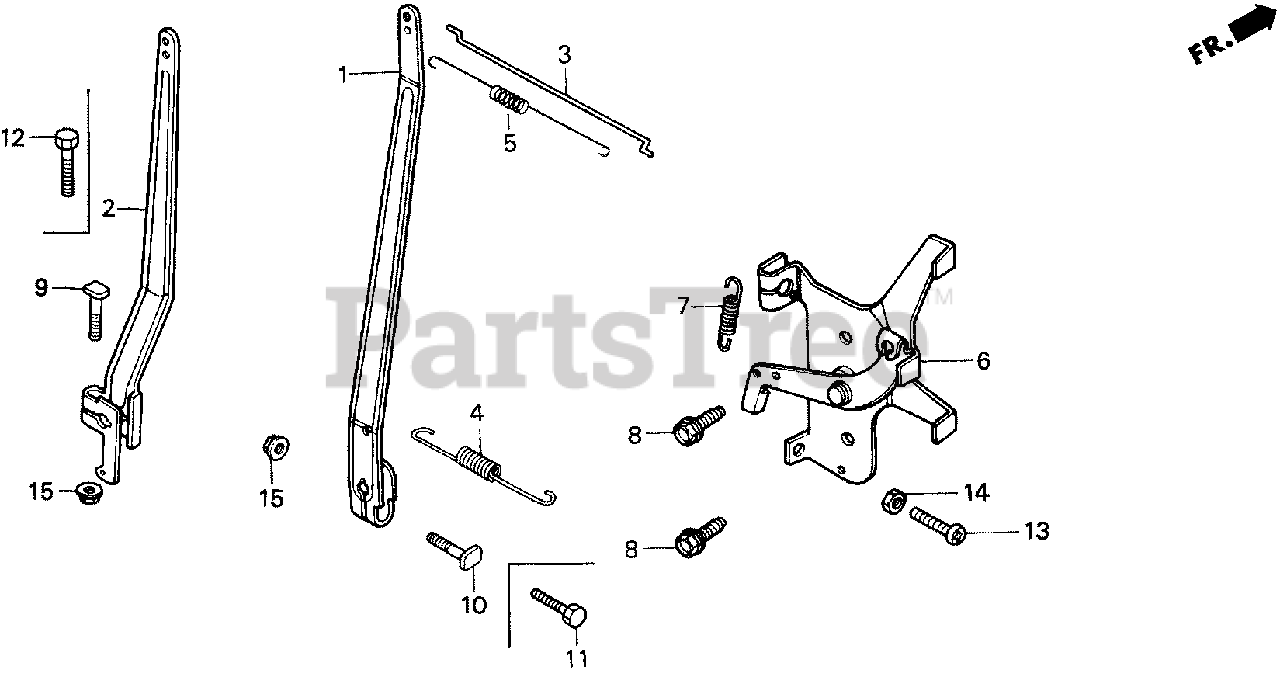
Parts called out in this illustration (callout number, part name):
1	ARM, GOVERNOR
3	ROD, GOVERNOR
4	SPRING, GOVERNOR
5	SPRING, THROTTLE RETURN
6	LEVER, CONTROL
7	SPRING, CABLE RETURN
8	BOLT, FLANGE (6X12) (CT200)
11	BOLT, HEX. (6X20)
13	SCREW, PAN (6X20)
13	SCREW, PAN (6X25)
14	NUT, HEX. (6MM)
15	NUT, FLANGE (6MM)
